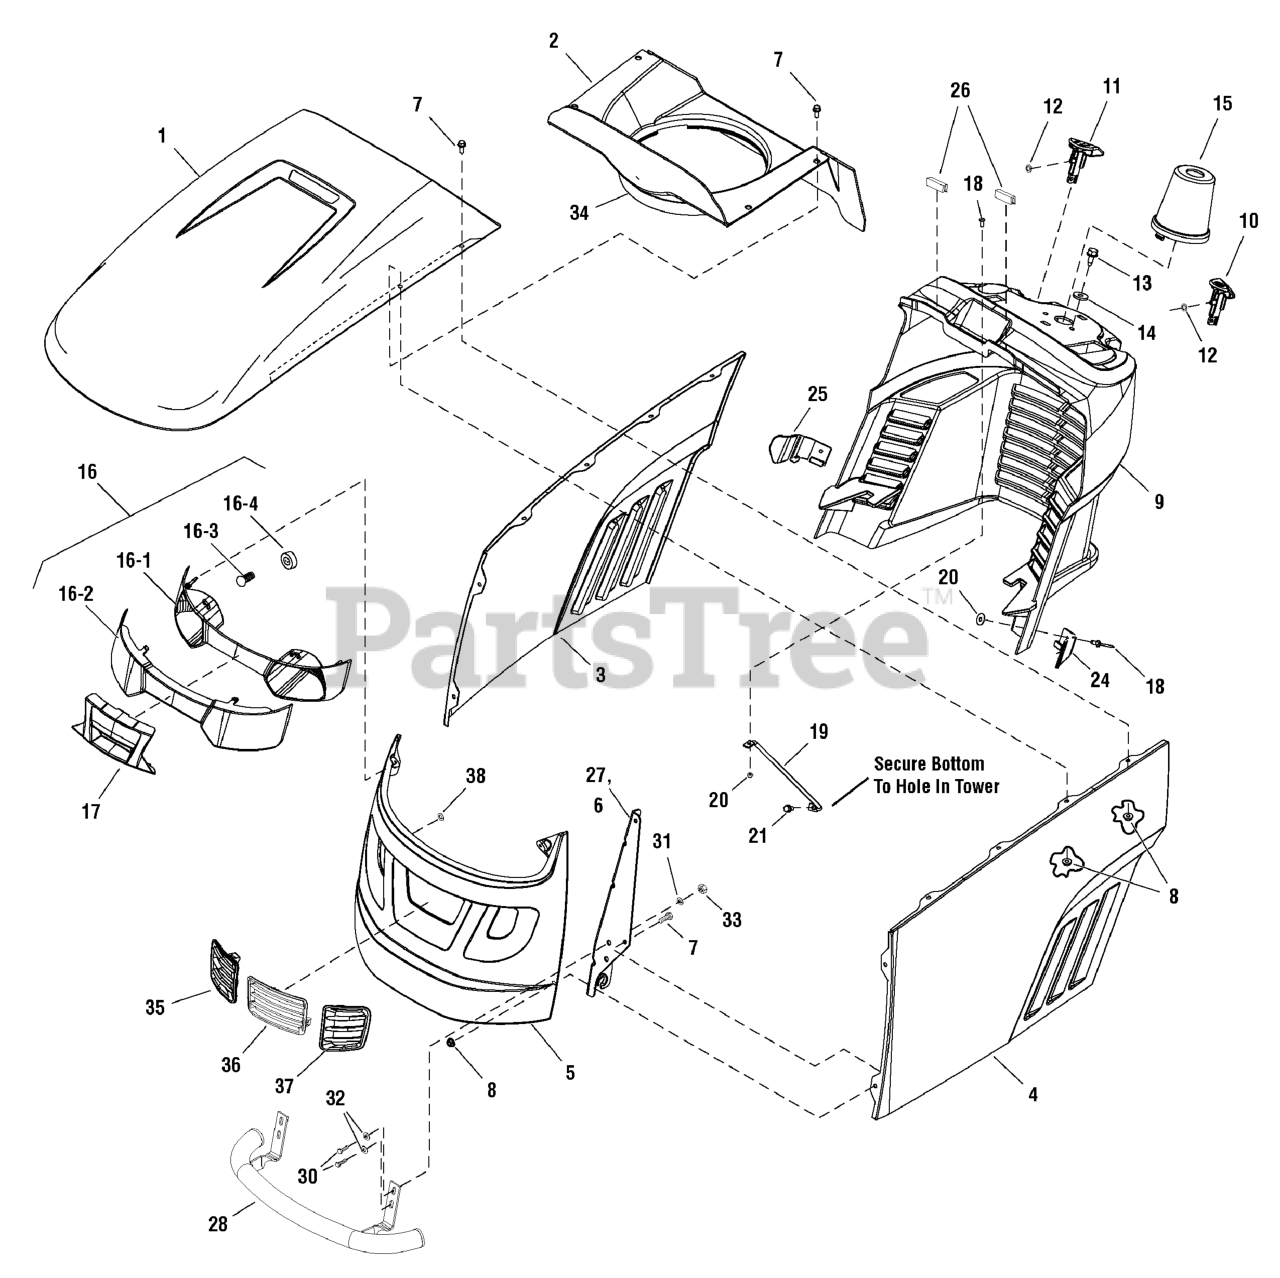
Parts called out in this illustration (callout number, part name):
1	HOOD, Black
2	DUCT, Air Inlet
3	PANEL, Side, R.H.
4	PANEL, Side, L.H.
5	GRILLE, Black
6	HINGE, Hood, L.H.
7	CAPSCREW, Hex Flange Whiz Lock, 1/4-20 x 5/8
8	NUT, Hex Flange, Whiz Lock, 1/4-20
10	KNOB, Brake Lock
11	KNOB, Cruise Lock
12	PUSHNUT, 1/4
13	CAPSCREW, Hex Washer Head, Taptite, 5/16-18 x 3/4
14	WASHER, 5/16
15	COVER, Steering Shaft
16	HEADLIGHT ASSEMBLY, Complete
16-1	REFLECTOR
16-2	LENS
16-3	BULB, 12V
17	INSERT, Lightbar
18	SCREW, Pan Head Phillips, #10-24 x 1
19	ROD, Dash Support, 10"
20	NUT, Nylon Insert Lock, 10-24
21	CAPSCREW, Hex Washer Head, Taptite, 1/4-20 x 1/2
24	GUIDE, Hood, L.H.
25	GUIDE, Hood, R.H.
26	BRAID, Steel Insert
27	HINGE, Hood, R.H.
28	BUMPER, Front
30	CAPSCREW, M8 x 40
31	WASHER, 8.4
32	WASHER, 8
34	EDGING, Rubber
35	INSERT, Grille, R.H.
36	INSERT, Grille, Center
37	INSERT, Grille, L.H.
